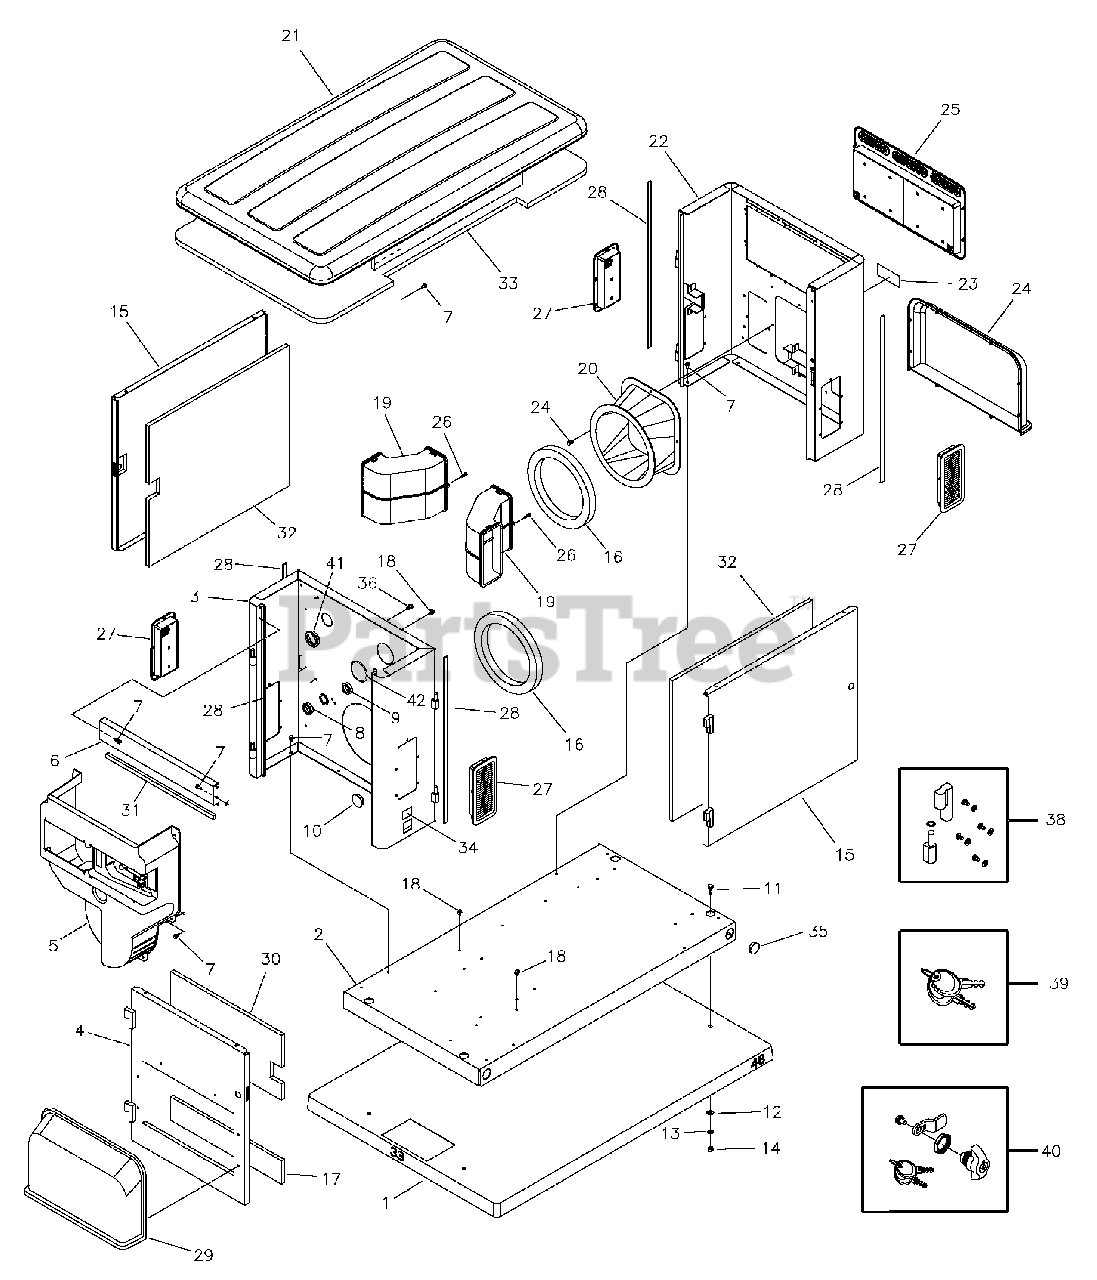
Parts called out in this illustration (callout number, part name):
1	PAD, Mounting w/ Holes
2	BASE, Mounting
3	BULKHEAD, Engine
4	ASSEMBLY, Door, Engine End
7	BOLT
9	BUSHING, Snap, 1-1/2
11	*CAPSCREW, Hex Head, 3/8-16 x 1
12	*WASHER, Flat, 3/8-M10
13	*WASHER, Lock, 3/8
14	*NUT, 3/8-16
17	INSULATION, Engine Door, Bottom
18	MOUNT, Tie Wrap
20	ADAPTER, Alternator
22	BULKHEAD, Alternator
24	COVER, Air Intake
25	ASSEMBLY, Vent, Exhaust
29	COVER, Air Intake, Engine
30	INSULATION, Engine Door, Top
34	DECAL
